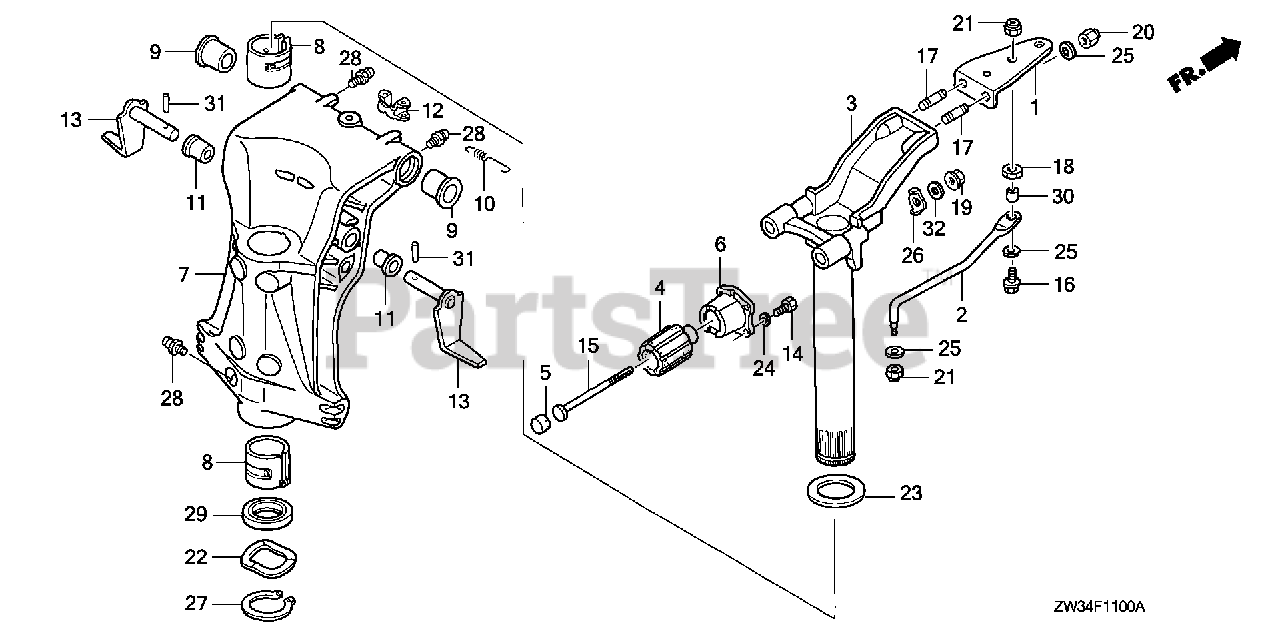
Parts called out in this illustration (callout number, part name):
1	PLATE, STEERING
2	ROD, STEERING
3	FRAME, MOUNTING
4	RUBBER, MOUNTING (UPPER)
5	RUBBER, MOUNTING (UPPER) (B)
6	HOLDER, MOUNTING (UPPER) *NH8* (DARK GRAY)
7	CASE, SWIVEL *NH282MU* (OYSTER SILVER METALLIC-U)
8	LINER, SWIVEL CASE
9	BUSH, SWIVEL CASE
10	SPRING, TILT LEVER
11	BUSH, TILT ARM
12	BRACKET, TILTING
13	STOPPER, TILT
14	BOLT, HEX. (6X18)
15	BOLT, SPECIAL (10X130)
16	BOLT (3/8-24 UNF)
17	BOLT, STUD (10X28)
18	NUT (3/8-24 UNF)
19	NUT, FLANGE (10MM)
20	NUT, SELF-LOCK (10MM)
21	NUT, SELF-LOCK (3/8-24UNF)
22	WASHER, WAVE (40MM)
23	WASHER, THRUST (34MM)
24	WASHER, PLAIN (6MM)
25	WASHER (10MM)
26	WASHER, SPECIAL
27	CIRCLIP (OUTER) (39MM)
28	NIPPLE, GREASE
29	OIL SEAL (39.5X52X6) (ARAI)
30	COLLAR, STEERING ROD
31	PIN, SPRING (2.5X20)
